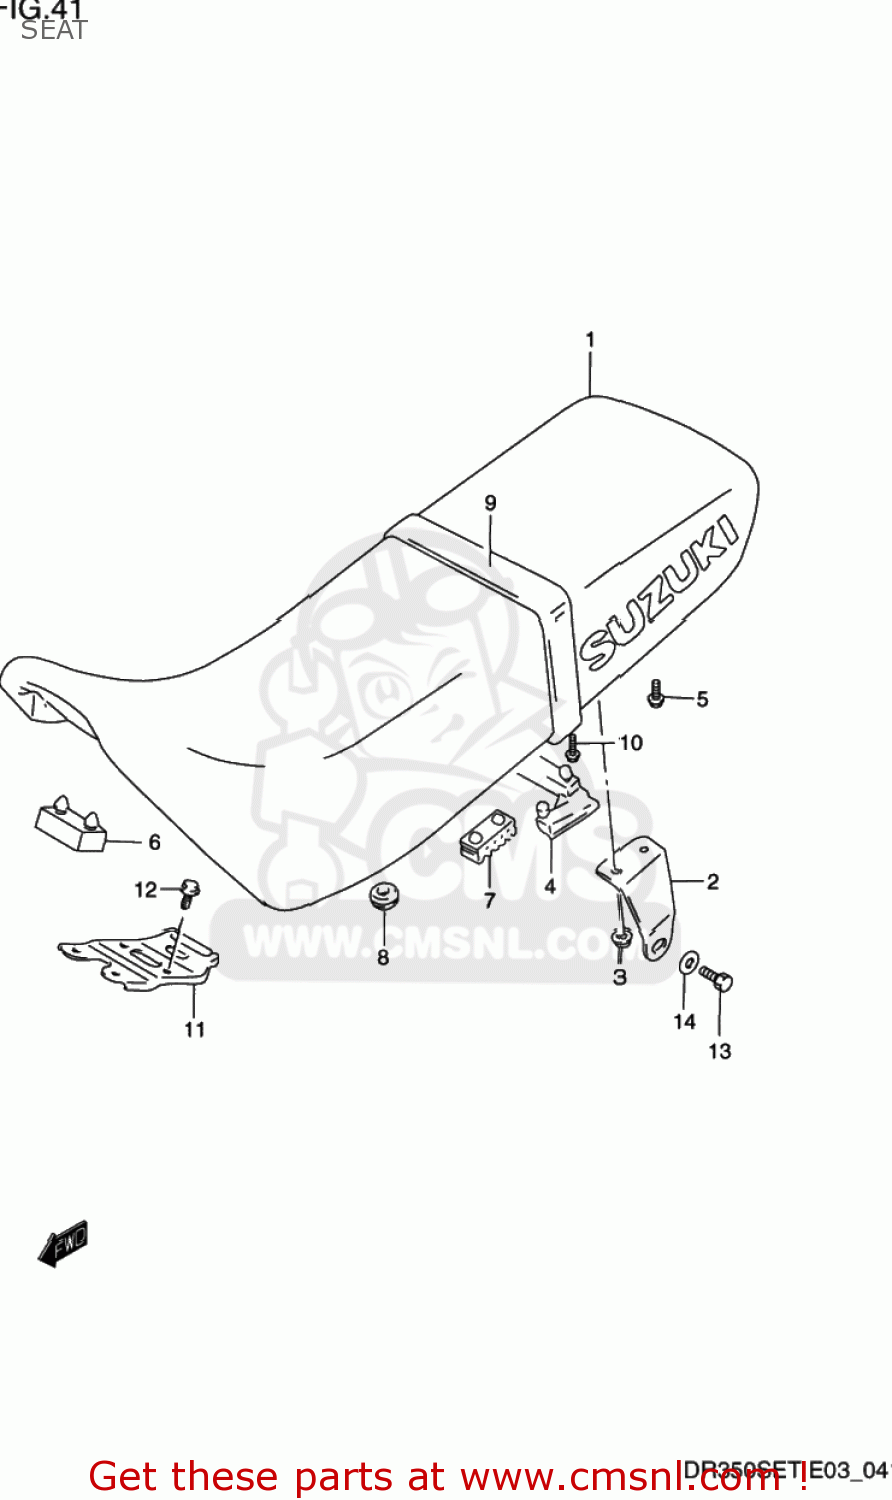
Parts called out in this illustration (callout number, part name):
1	SEAT SET
2	BRACKET,SEAT,R
3	NUT
4	CUSHION
5	BOLT
6	CUSHION
7	CUSHION,SEAT(40X20X15)
8	CUSHION
9	BAND ASSY,SEAT
10	BOLT
11	PLATE,SEAT FR HOOK
12	BOLT
13	BOLT
14	WASHER
